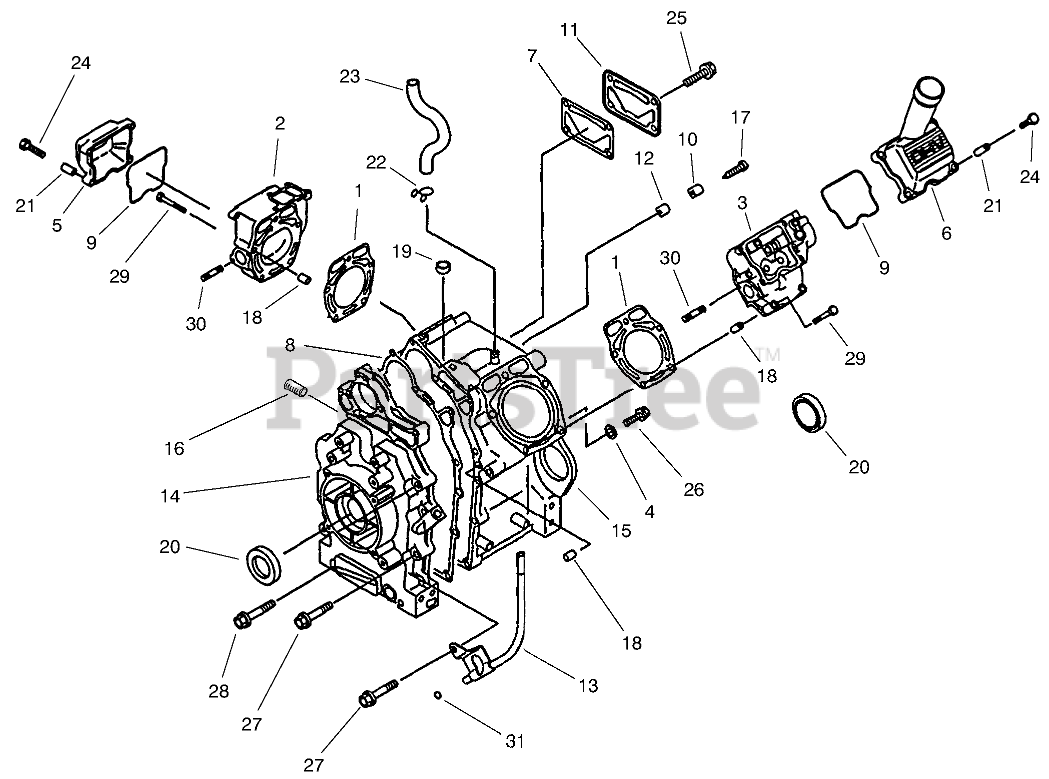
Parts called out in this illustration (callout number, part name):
1	GASKET HEAD
2	HEAD COMP CYL
3	HEAD COMP CYL
4	GASKET
5	CASE-ROCKER
6	CASE-ROCKER
7	GASKET
8	GASKET-CRANKCASE COVER
9	GASKET-ROCKERCASE
10	PLATE
11	COVER
12	VALVE
13	PIPE - OIL LEVEL
14	COVER-CRANKCASE
15	Crankcase-Comp
16	JOINT
17	SCREW
19	SEAL-OIL, VC (6X10X2.5)
20	SEAL-OIL
21	COLLAR
22	CLAMP
24	BOLT-FLANGED (6X25)
25	BOLT-FLANGED
26	BOLT-FLANGED
27	BOLT-FLANGED
28	BOLT-FLANGED
29	BOLT-FLANGED
30	BOLT-STUD
31	O-RING
